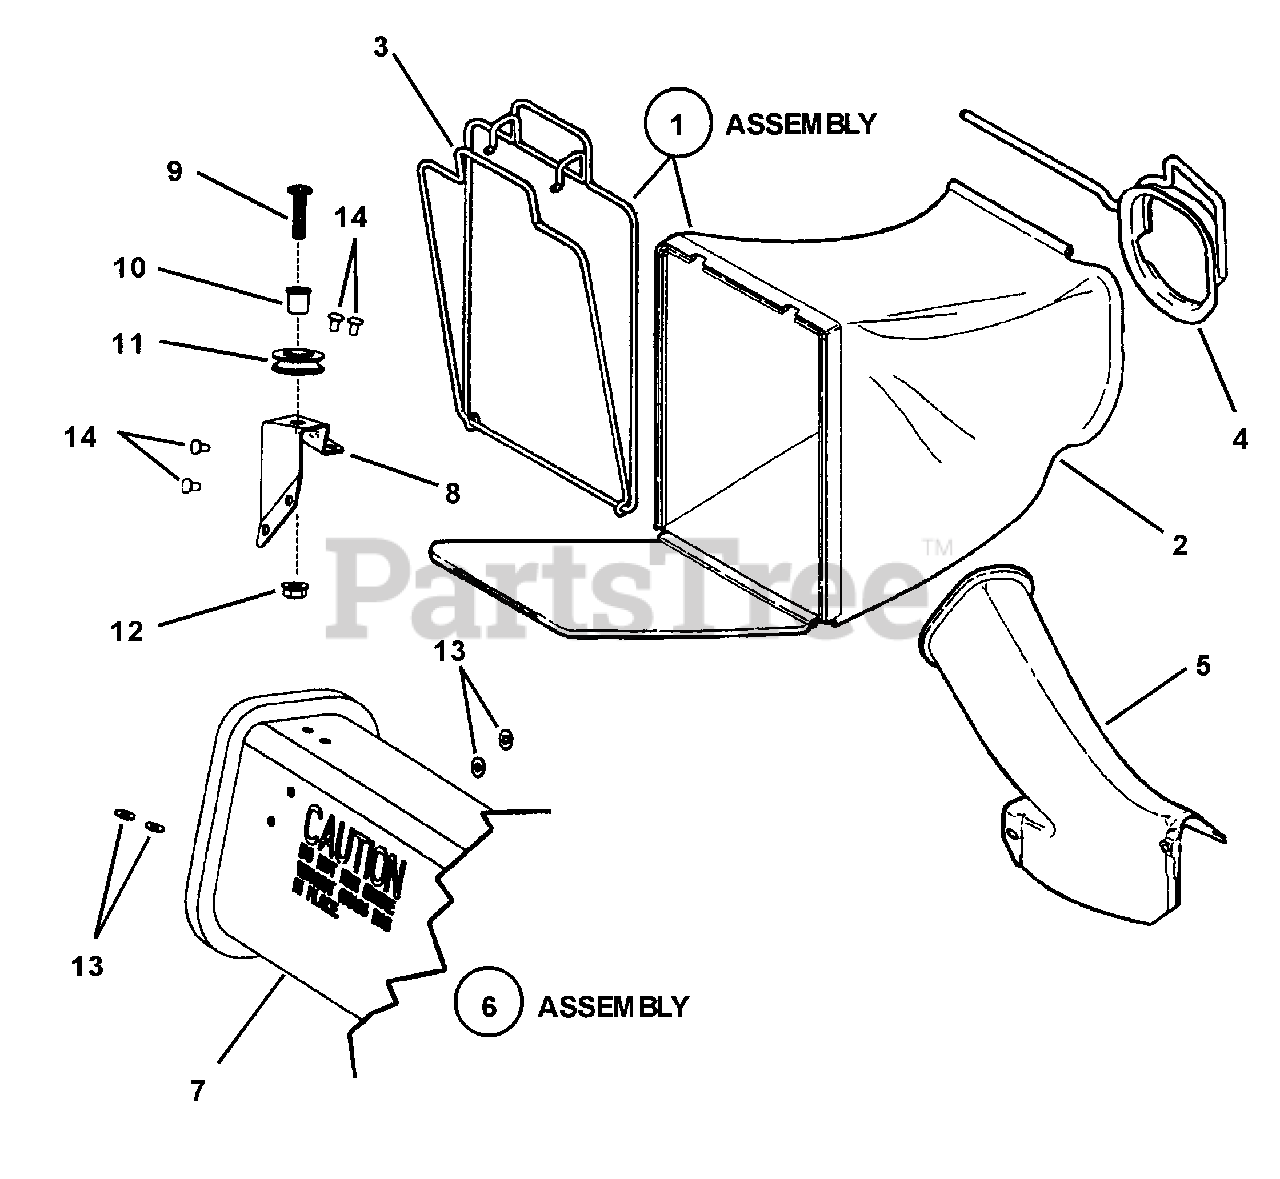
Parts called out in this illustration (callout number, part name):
1	ASSEMBLY, Grass Bag
2	BAG, Door Type (Wide) (Black) (13" Wide)
3	ASSEMBLY, Bag Wire (13" Wide)
4	CONNECTOR, Grass Bag
5	ADAPTER, Bag
6	ASSEMBLY, Bag Adapter
7	ADAPTER, Bag
8	BRACKET, Rope Pulley
9	SCREW, 5/16-18 x 1-1/4" Pan Head Machine
10	BUSHING, Flange
11	PULLEY, Plastic
12	NUT, 5/16-18 Hex Flange Lock, Grade 5
13	WASHER, 15/32"
14	RIVET, 3/16 x .344
